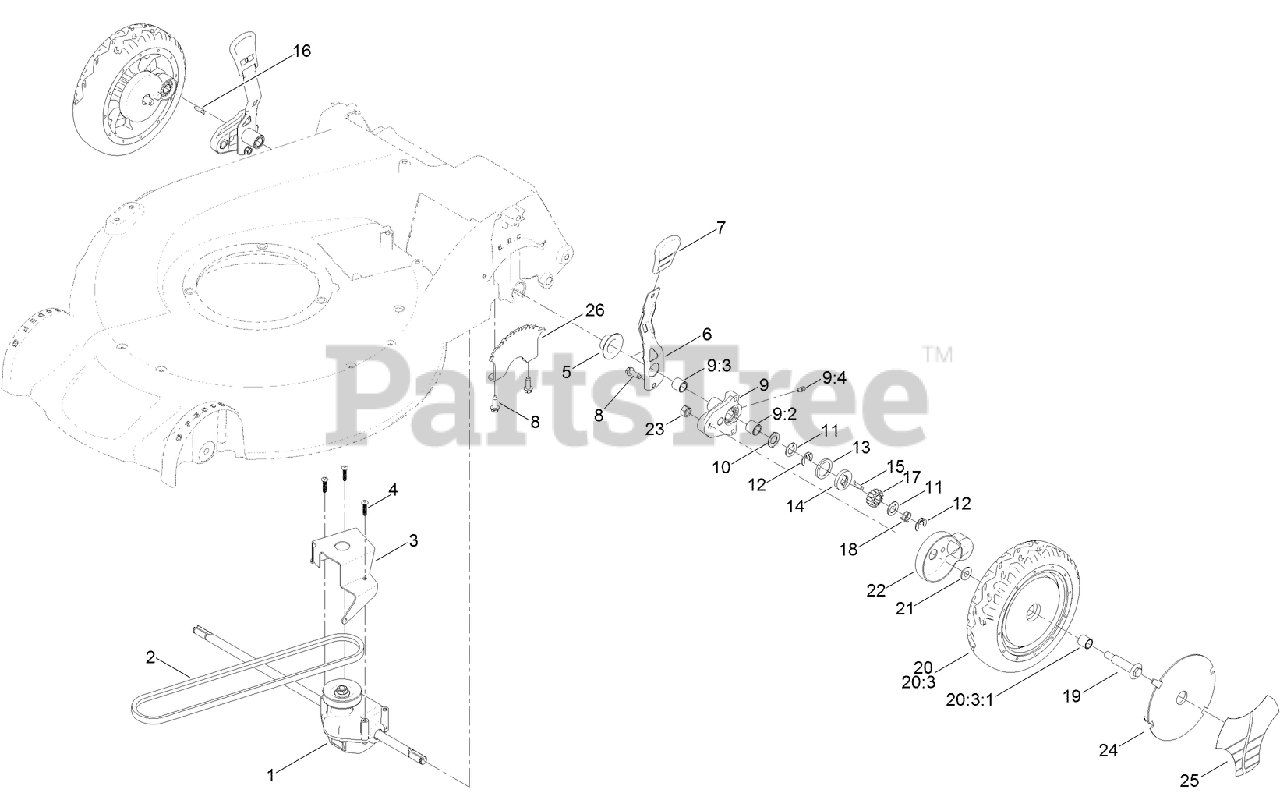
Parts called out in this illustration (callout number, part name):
1	TRANSMISSION ASM
2	BELT-V
3	BRACKET-TRANSMISSION
4	SCREW-PLASTITE
5	CAP-END
6	ARM-SPRING
7	KNOB-HOC
8	SCREW-HWHTF
9	PIVOT ARM ASM
9:2	BUSHING
9:3	BUSHING
9:4	FITTING-GREASE
10	WASHER-ARM, PIVOT
11	WASHER-THRUST, KEYED
12	RING-RETAINING,CLIP
13	RING-FRICTION
14	WASHER-CLUTCH
15	KEY-ROCKING, LH
16	KEY-ROCKING, RH
17	GEAR-PINION
18	SPRING-COMPRESSION
19	BOLT-SHOULDER
20	8 INCH WHEEL AND GEAR ASM
20:3	Loose Parts Package
20:3:1	BUSHING
21	SPACER-COVER, WHEEL
22	COVER-WHEEL
23	NUT-HEX
24	COVER-WHEEL
25	LABEL-WHEEL, SMART
26	PLATE-HOC
